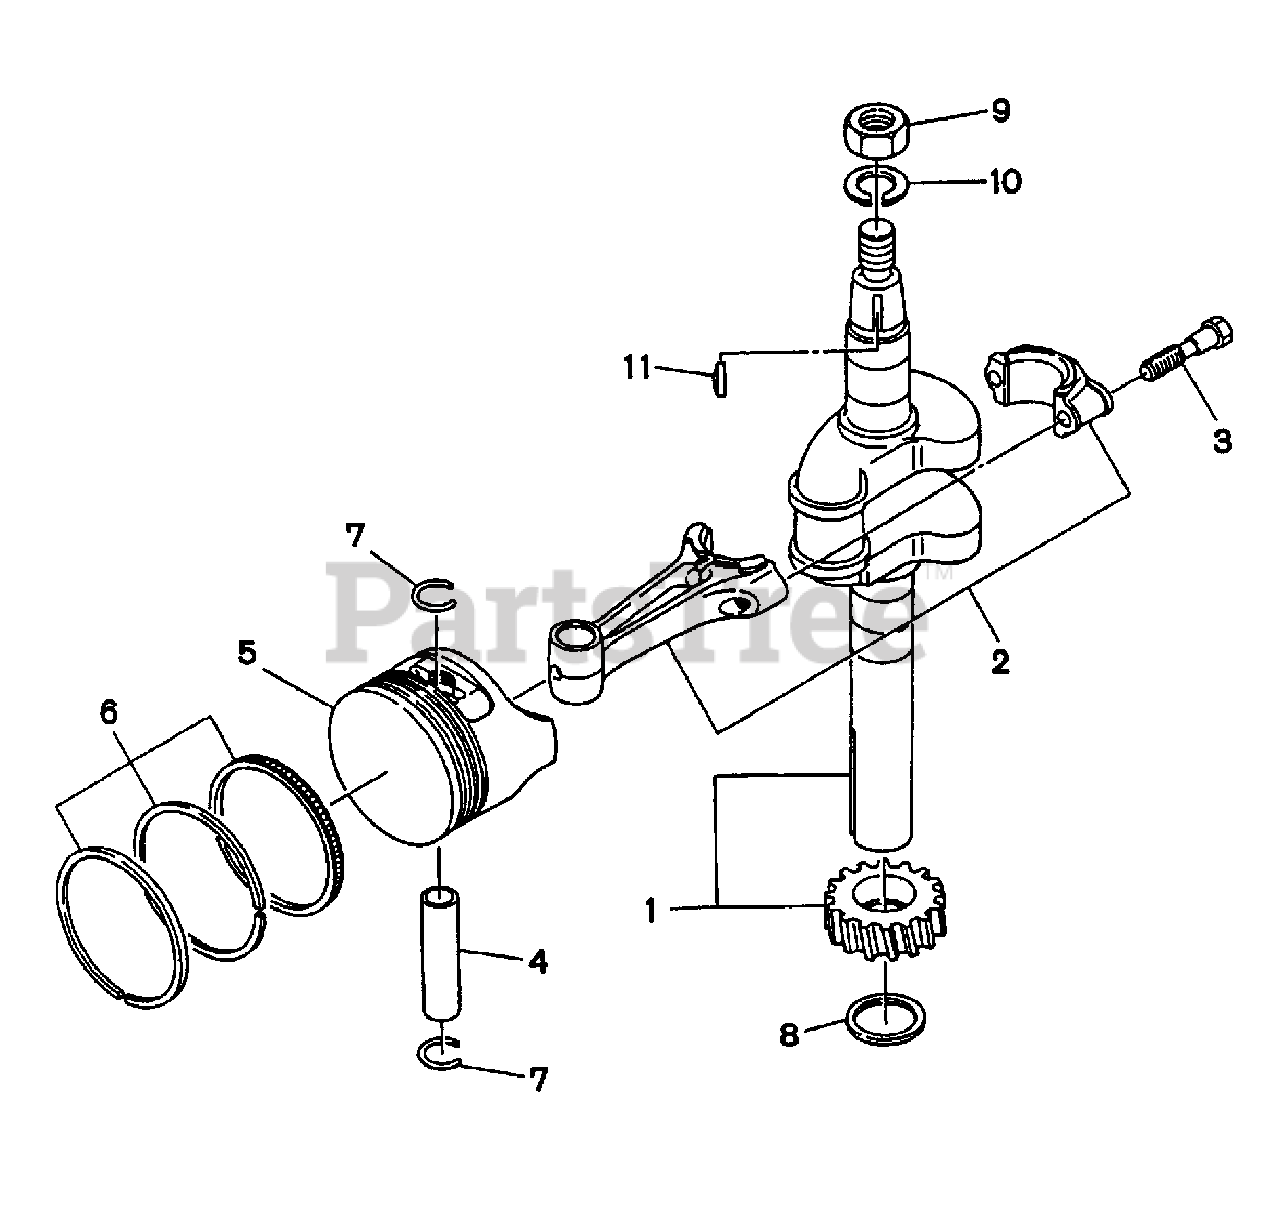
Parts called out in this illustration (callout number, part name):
1	CRANKSHAFT, compl., 25mm
1	CRANKSHAFT, compl., 7/8"
2	CONNECTING ROD ASS'Y
3	CONNECTING ROD BOLT
5	PISTON
6	PISTON RING SET
8	SPACER
10	SPRING WASHER
11	WOODRUFF KEY
